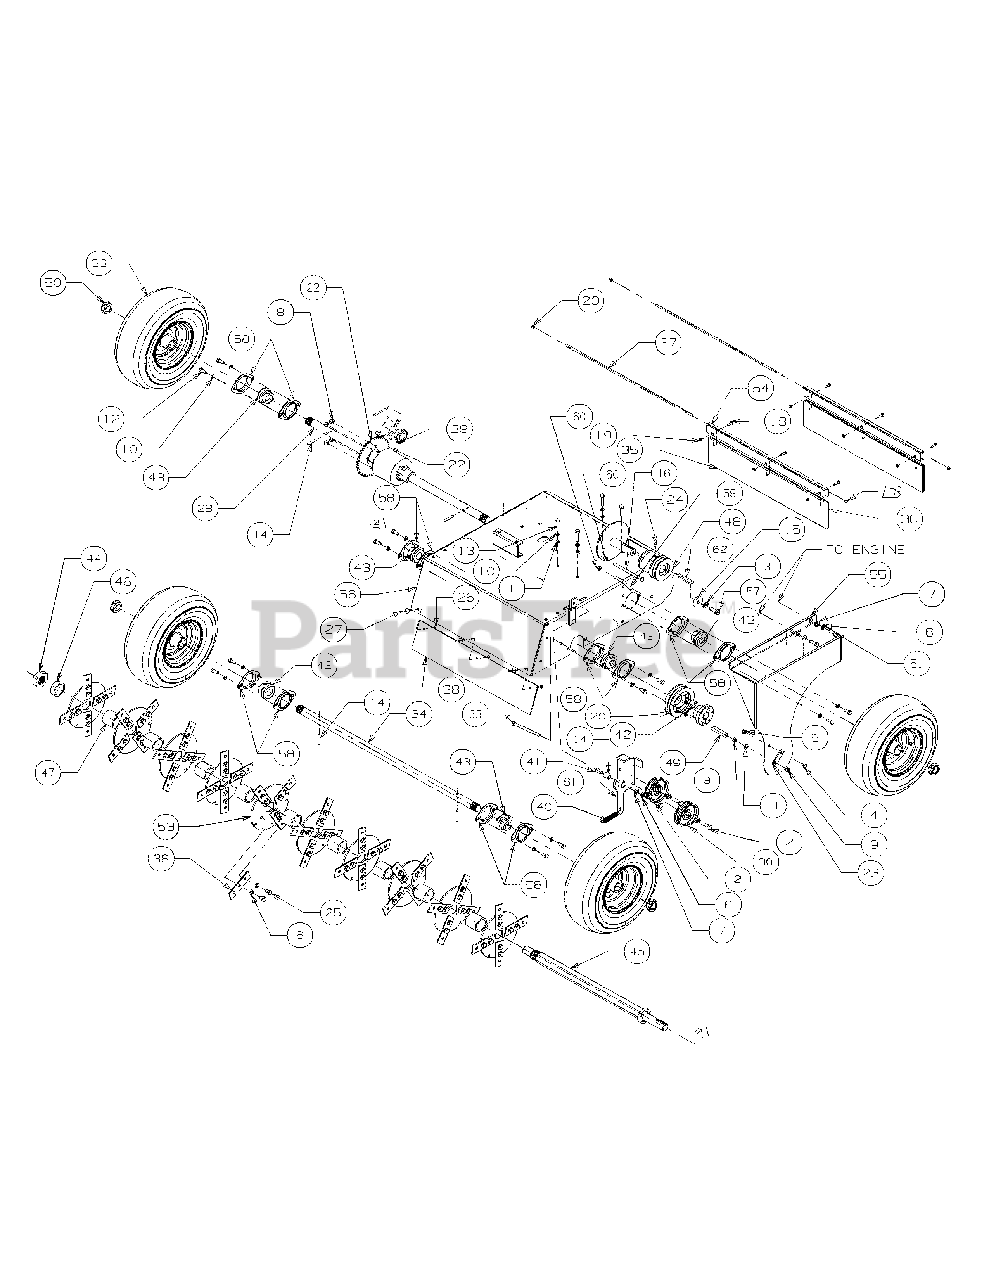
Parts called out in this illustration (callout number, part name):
1	Flat Washer, 5/16
2	Hex Cap Screw, 3/8-16 x 1-1/2
3	Lock Washer, M10
4	Hex Cap Screw, 1/4-20 x 1/2
5	Lock Nut, Nylon Insert, 1/4-20
6	Lock Washer, 3/8
7	Flat Washer, 3/8
8	Nylock Nut, 5/16-18
9	Hex Nut, 5/16-18
10	Lock Washer, 5/16
11	Flat Washer, 5/16
12	Hex Cap Screw, 5/16-18 x 3/4
13	Hex Cap Screw, 5/16-18 x 1-1/2
14	Groove Pin, 1/4 x 1-1/2
15	Clutch Washer
16	Hex Cap Screw, M8-1.25, 120.0
17	Chain, Master Link 21-1/2
18	Round Head Machine Screw, 10-32 x 3/4
19	Nut, Keeper, #10-32
20	Sheave Pulley
21	Sheave Bushing
23	Belt Guard Bracket
24	Cap Screw, 5/16-18 x 5/16
25	Hex Cap Screw, 3/8-24 x 1/2
26	Flat Washer, 3/16
27	POP, Rivet, 3/16
28	Differential
29	Push-On Cap, 1/4
31	Power Wedge COG 26.1" OD, Pump Belt
32	2 Rib Blade Belt
33	Wheel Assy, 13-5 x 6
34	Shaft Agitator
36	Brush Guard
37	Brush Mounting Shaft
38	Heavy Duty Blade
39	Sprocket Drive Motor
40	Reel Enlargement Spring
41	Bellecrank Pivot Tube
42	Key, 1/4 x 1/4 x 1-1/4
43	Flanged Ball Bearing
44	Hex Lock Nut, 1-1/4-12
45	Disc Shaft Assembly
46	Disc Blade Spacer Assembly
47	Blade Disc Spacer
48	Double Pulley, 2.65 Dia. 3.15 Dia.
49	Spacer, Stop Deck
50	Jam Nut Insertion Lock, 1.0 -14
51	Hex Cap Screw, M8-1.25 x 25mm
53	Disc Blade
54	Brush Clip Assembly
55	Belt Guard Assembly
56	Power Deck Assembly
57	Hex Cap Screw, M10x1.5, 30mm, GR10.9
58	Flange Bearing Cover
59	Belt Guide Rod, M8-1.25
60	Hex Nut Center Lock, M8
61	Blade Clutch with Bearings, Bellecrank Assembly
62	Key, 1/4 x 1/4 x 2-3/4
63	Tap Bolt, 5/16-18 x 4.00
